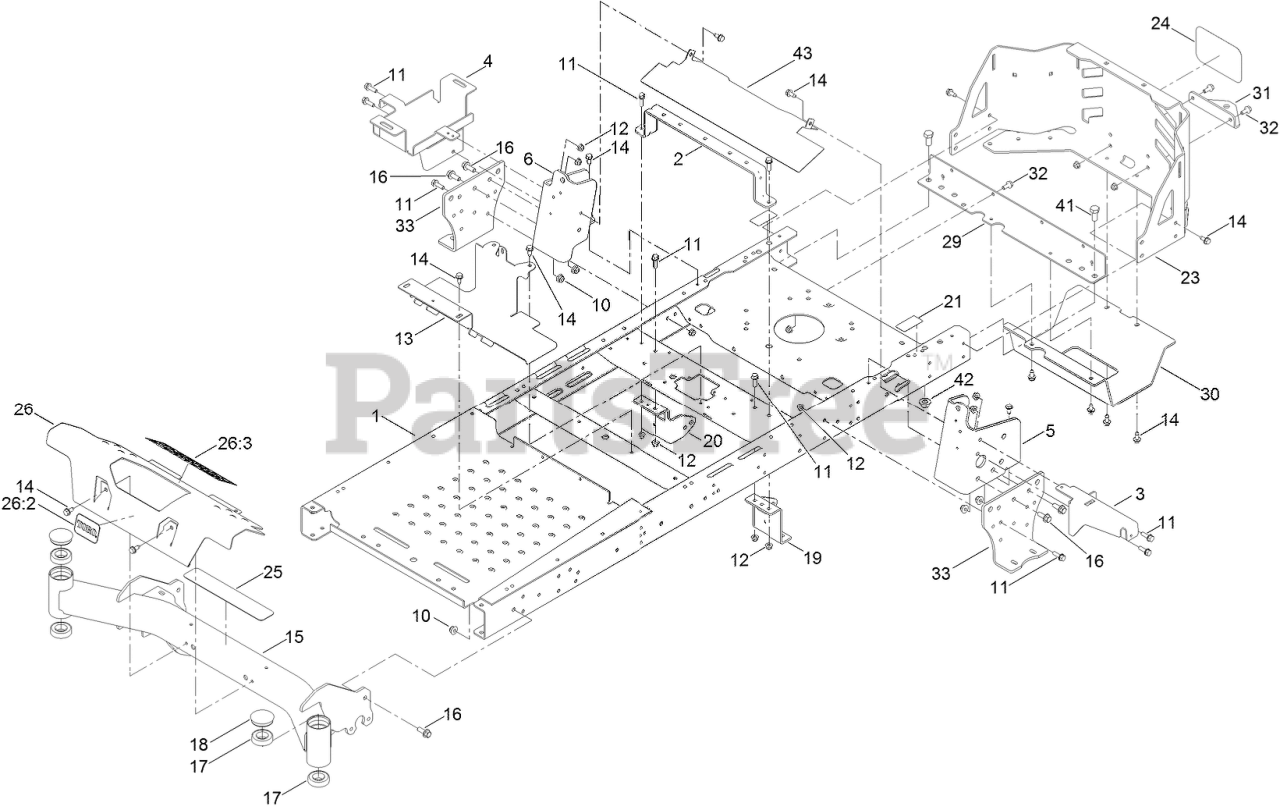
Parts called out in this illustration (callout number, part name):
1	FRAME ASM
2	BRACE-SEAT, REAR (WIDE)
3	BRACKET-SUPPORT, POD (LH)
4	TRAY-BATTERY
5	BRACKET-MOUNTING, LH
6	BRACKET-MOUNTING, RH
10	NUT-HF, NI
11	SCREW-HHF
12	NUT-HF, NI
13	BRACKET-MOUNT
14	SCREW-HWHTF
15	AXLE-FRONT
16	SCREW-HHF
17	BEARING-BALL
18	CAP-GREASE
19	MOUNT-HYDRO, FRONT (LEFT)
20	MOUNT-HYDRO, FRONT (RIGHT)
21	DECAL-BYPASS
23	GUARD-ENGINE
24	DECAL
25	TREAD-STEP
26	FOOTREST
26:2	Decal
26:3	DECAL-DANGER
29	CROSSMEMBER-REAR
30	GUARD-MUFFLER
31	BRACKET-HITCH
32	SCREW-HHF
33	MOUNT-HYDRO
41	SCREW-HH
42	NUT-LOCK
